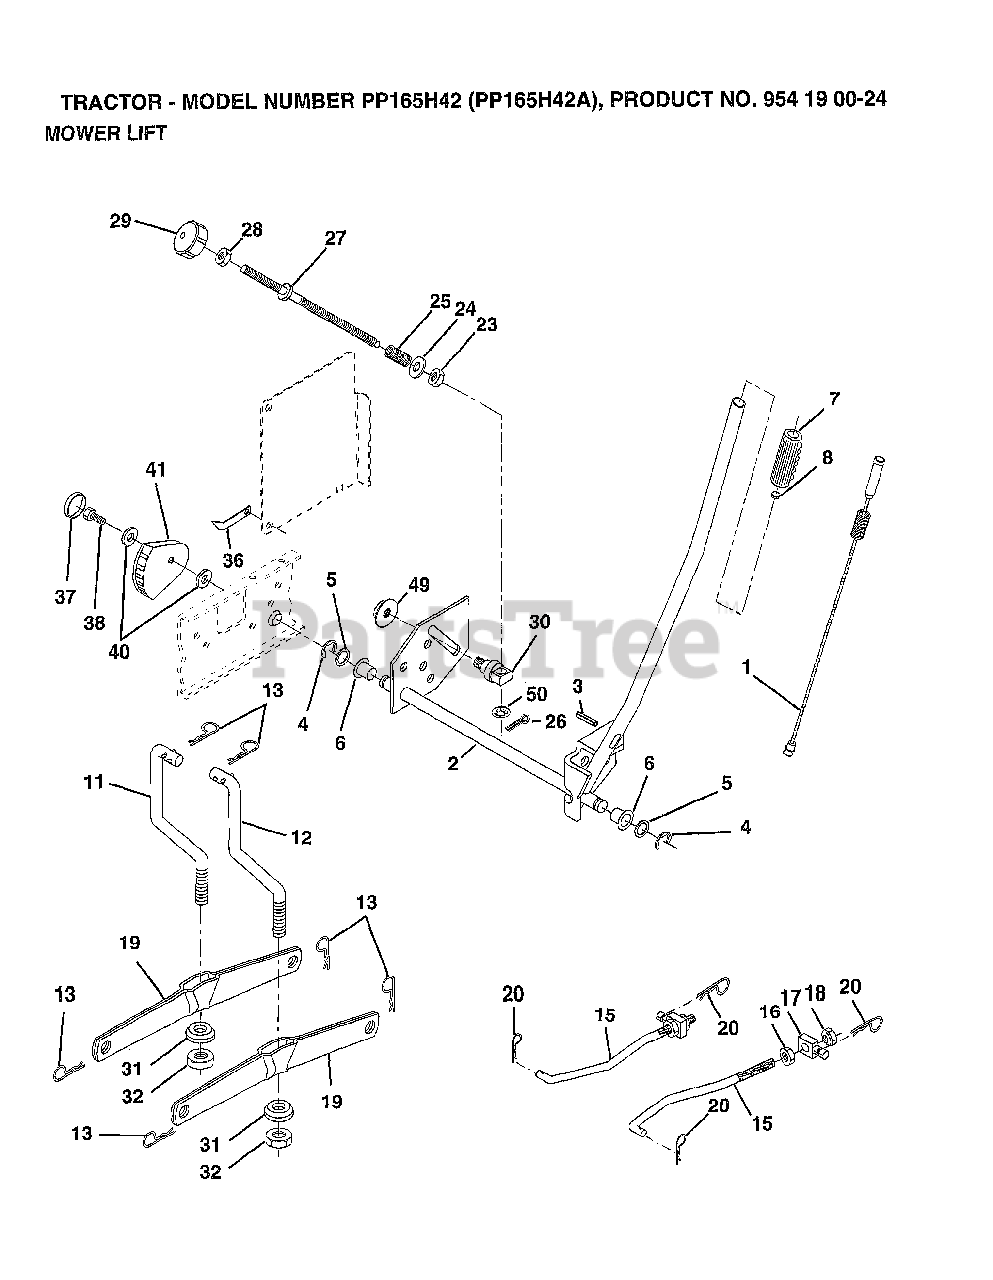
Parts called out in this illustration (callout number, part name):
1	WIRE ASM W.SPRING
2	"SHAFT ASM LIFT,RH"
3	PIN-GROOVE LT
5	WASHER
6	NYLON BEARING
7	GRIP
15	LINK.FRONT
16	NUT
17	TRUNION
18	NUT.LK.W/WSH.1/2.
19	ARM SUSP REAR
20	RETAINER SPRING
23	NUT T
24	WASHER
25	SPRING T
28	NUT
29	KNOB INF 3/8-16
30	TRUNNION
31	BEARING PVT LH
32	NUT.CROWNLOCK.3/8
36	POINTER-INDICAT
37	"PLUG,HOLE"
38	SCREW
40	WASHER
41	INDICATOR HEIGHT
49	NUT.HXFLG.LOCK.
